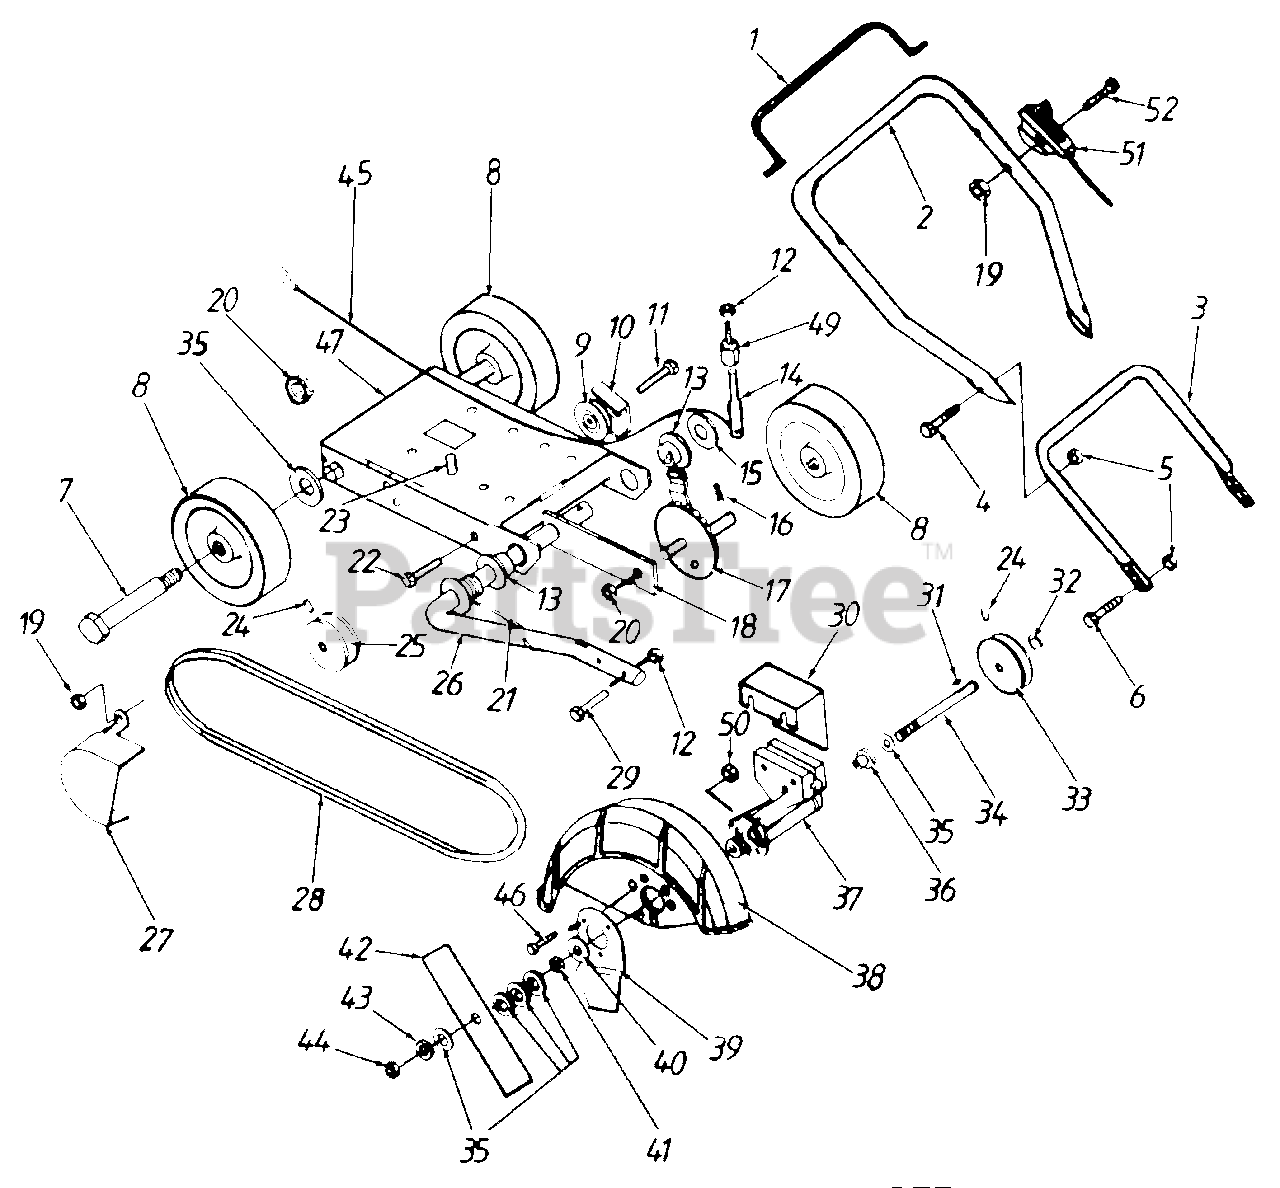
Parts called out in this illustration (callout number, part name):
1	Lever-Depth Control
2	Upper Handle
3	Lower Handle
4	Hex Bolt 5/16-18 x 1.5"
5	Hex Keps L-Nut 5/16-18 Thd.
6	Hex Bolt 5/16-18 x .625"
7	Wheel Bolt
8	Wheel 6"
9	Idler Pulley
10	Bracket-Idler Pulley
11	Bolt
12	Hex L-Nut 5/16-18 Thd.
13	Bushing
14	Arm-Pivot Rod
15	Flat Washer 5/8" I.D.
16	Cotter Pin 1/8 x 3/4"
17	Adjustor Assembly
18	Arm-Front Wheel
19	Hex L-Nut 1/4-20 Thd.
20	Hex Keps L-Nut 3/8-16 Thd.
21	Spring-Cutterhead
22	Hex Bolt 5/16-18 x 1"
23	Engine Bolt
24	Locking Set Screw 5/16-18
25	Pulley Engine
26	Rod Cutterhead
27	Belt Guard
28	V-Belt
29	Hex Bolt 5/16-18 x 1.5"
30	Belt Guard
31	Woodruff Key
32	Retaining Ring
33	Pulley Cutterhead
34	Shaft Cutterhead
35	Flat Washer .063" Thk.
36	Bushing Cutterhead
37	Housing Cutterhead Shaft
38	Blade Guard
39	Edge Guide
40	Flat Washer .035 Thk.
41	Heavy Hex Jam Nut 3/8 24
42	9 Replacement Blade
43	Spring L-Wash. 3/8" I.D.
44	Hex Nut 3/8-24 Thd.
45	Cable Depth Control
46	Hex Bolt #10-24 x .75'
47	Base Edger Frame
49	Spacer Pivot Arm
50	Nylok Nut #10-24
51	Throttle Control
52	Hex Bolt 1/4-20 x 1.5"
